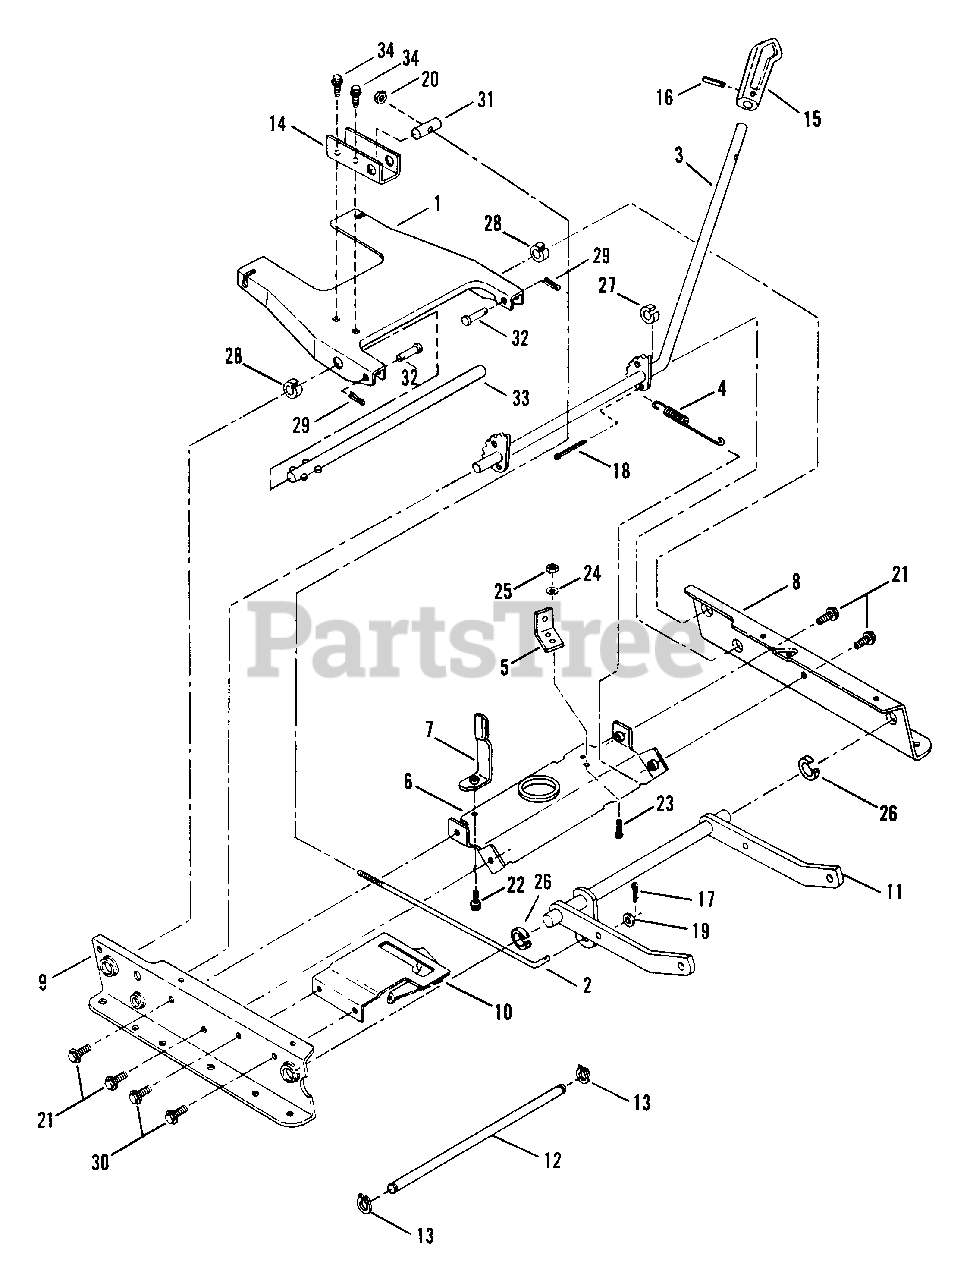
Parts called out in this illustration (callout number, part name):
1	REAR LIFT ARM
2	ROD, Leveling
3	WELDMENT, Lift Lever
4	SPRING, Cam lift
5	ANCHOR
6	BRACE, Top
7	GUIDE, Belt
8	RAIL, Left Hand
9	RAIL, Right Hand
10	ASSEMBLY, Clutch-Plate
11	FRONT LIFT ARM, Non-Adjustable
12	SUPPORT ROD (Front Lift Arm to Front End)
13	RING, Retaining
14	ARM, Leveling
15	GRIP, Height Adjustment Lever
16	ROLL-PIN
17	PIN, 1/8 x 3/4" Cotter
18	PIN, 5/32 x 1" Cotter
19	WASHER, 3/8" Flat
20	NUT, 3/8 - 24 Hex
21	SCREW, 3/8 - 16 x 1/2" Hex Hd., Self-Tapping
22	SCREW, 5/16 - 18 x 5/8" Hex Self-Tapping
23	SCREW, 5/16 - 24 x 3/4" Hex Head Cap
24	LOCKWASHER, 5/16 Internal Tooth Lock
25	NUT, 5/16-24 Hex
26	RING, Red
27	RING, White
28	RING, White
29	PIN, 3/32 x 3/4" Cotter
30	SCREW, 5/16 - 18 x 1/2" Self-Tapping
31	PIVOT, Leveling
32	PIN, 3/8 x 1 1/16" Clevis
33	SHAFT, Pivot
34	SCREW, 3/8-16 x 1/2" Self-Tapping
